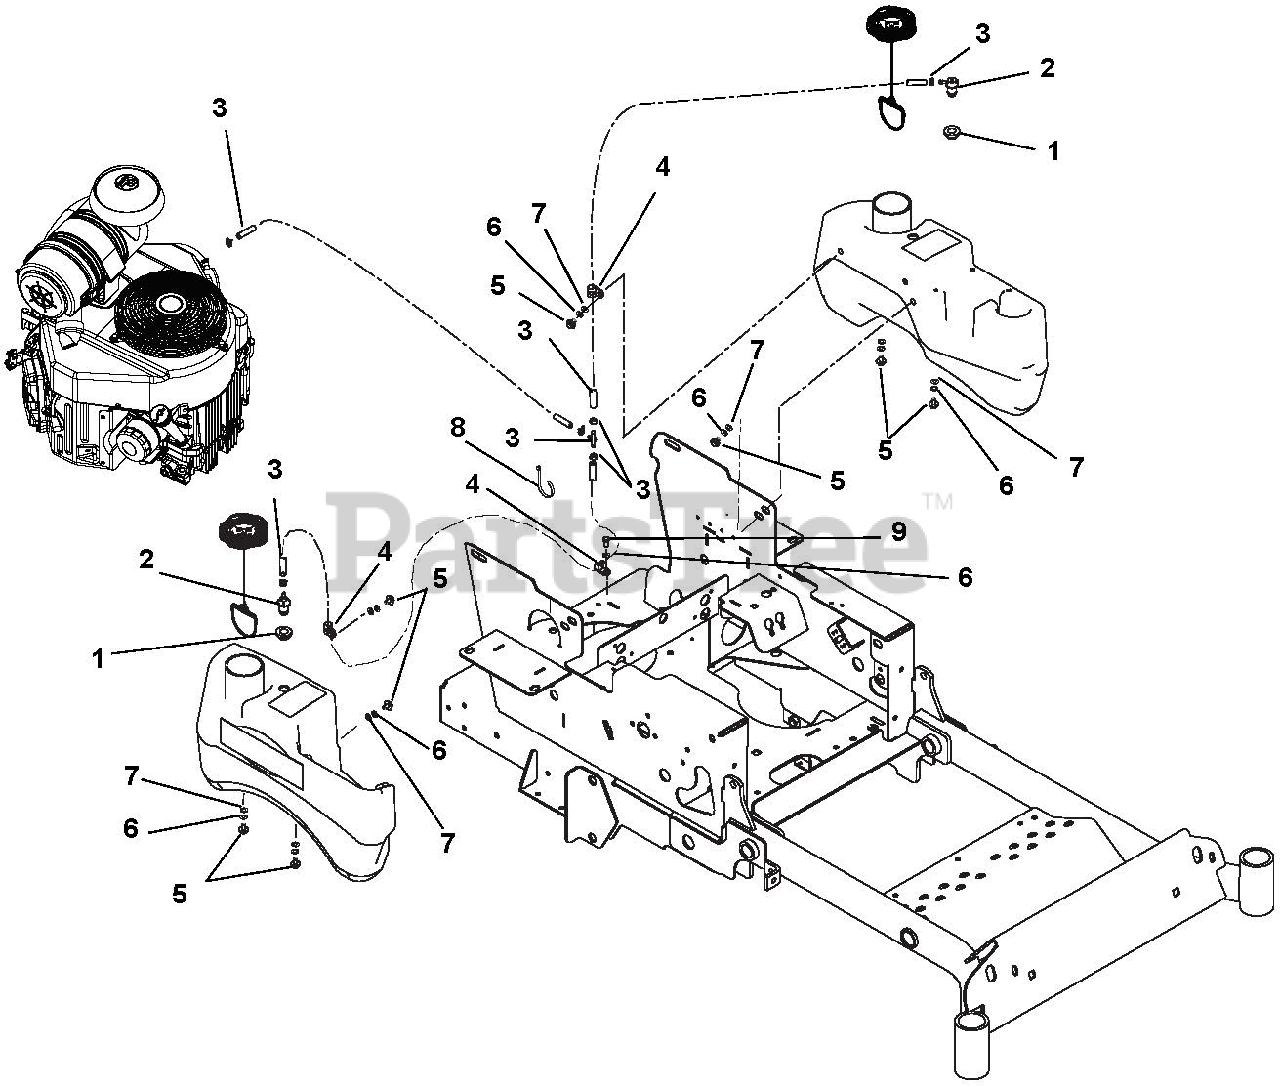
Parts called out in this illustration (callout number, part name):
1	Grommet, 2-way
2	Valve, 2-way
3	CP44, Fuel Line Assembly
5	Bolt, .31-18 x .62
6	Washer, Locking .31 x .078 Regular
7	Washer, Flat Steel .38 x .875 x .083
8	Tie, Cable LG 5.50
9	Bolt, Hex M8-1.25 x 2.0
